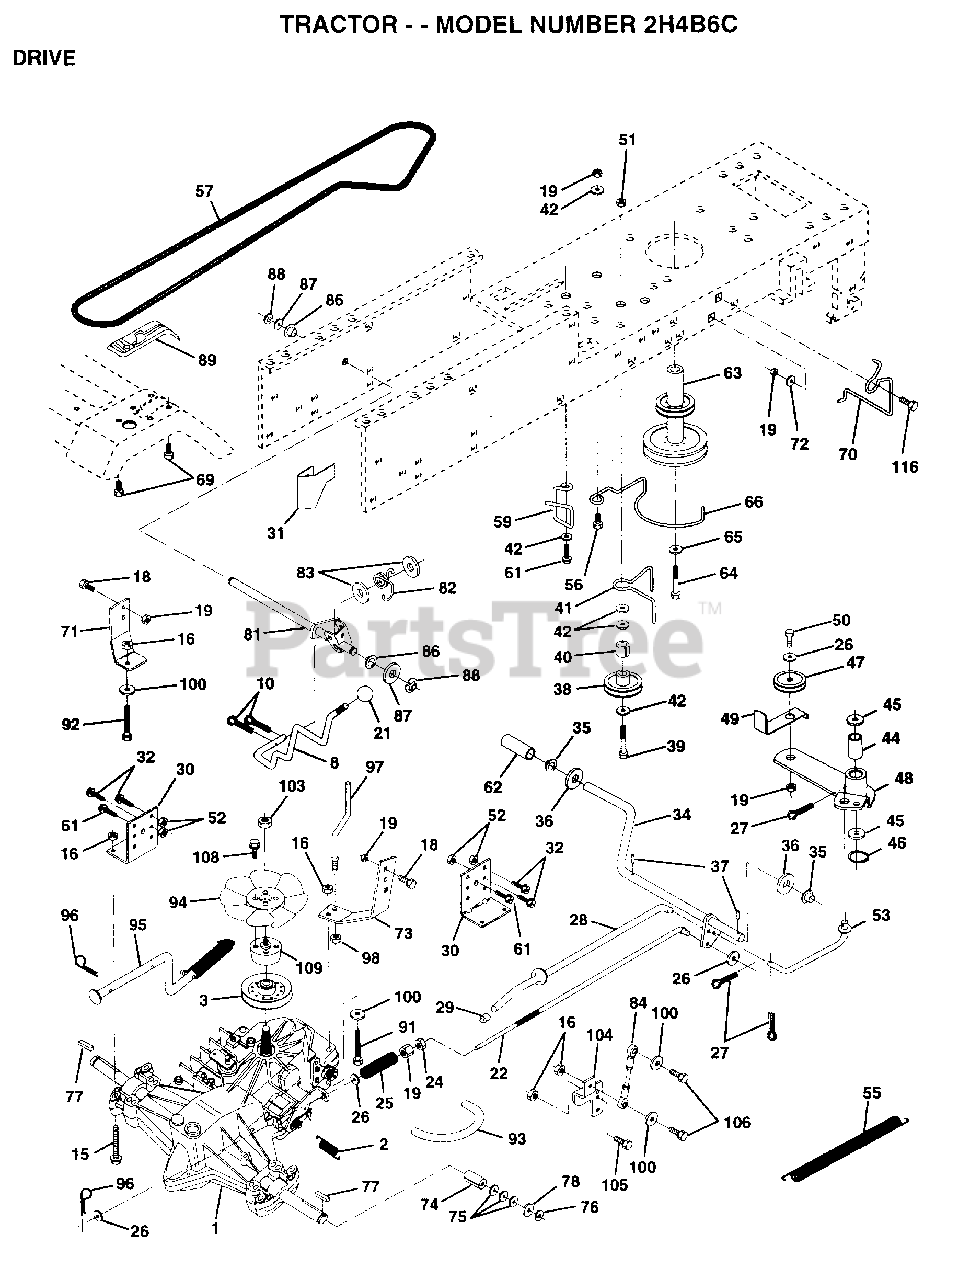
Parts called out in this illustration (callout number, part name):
1	TRANSAXLE HYD 0319-0500
2	SPRING RET BRAKE
3	PULLEY.4.20.HYDRO
8	ROD SHIFT FEND LT
10	PIN COTTER 1/8
15	BOLT.HX.FLG.5/16
16	NUT
18	BOLT
19	NUT
21	KNOB T (1/2-HOLE)
22	ROD.BRAKE.HYDRO.
24	NUT
25	SPRING ROD LT
26	WASHER
27	COTTER PIN
28	ROD.BRAKE.PARK.LT
29	PLUNGER CAP T
30	TRANSAXLE MTG BKT
31	"KEEPER,BELT LH T"
32	BOLT
34	SHAFT.PEDAL.FOOT
35	NYLON BEARING
36	WASHER LT
38	PULLEY.IDLER.FLAT
39	BOLT
40	SPACER T
41	BELT KEEPER LT
42	WASHER
44	"LY, BEARING"
45	WASHER LT
46	KLIP RING
48	ARM IDLER
49	RETAIN BELT
53	"LINK, CLUTCH T"
55	"SPRING, RETURN LT"
57	BELT-V.HYDR.84.61
59	KEEPER BELT CNTSP
61	SCREW
62	PEDAL COVER T
63	PULLEY.ENGINE
64	BOLT
65	LOCKWASHER
66	KEEPER.BELT.ENG.L
69	SCREW HEXWSH H-L
70	KEEPER BELT ENG
71	STRAP.TORQ.LH.HYD
72	WASHER
73	STRAP.TORQ.RH.HYD
74	SPACER SPLIT
75	WASHER
76	E-RING LT
77	SQUARE KEY
78	WASHER
81	SHAFT.CROSS.HYD
82	"SPRING,TORSION"
83	WASHER
84	ROD.TIE.BALL.HYD.
86	BUSHING
87	WASHER D
88	KLIP RING
92	HEX BOLT
93	"LINE FUEL HYD 4"""
94	"FAN 7"" HYDRO"
95	RETAINER M
97	KEEPER.BELT.RH.HY
98	NUT
100	WASHER M
104	ARM.CONTROL.PUMP
105	SCREW CAP 5/16-18
106	BOLT
108	SCREW.HXHD.10-20
109	ADAPTOR.FAN.HYDRO
116	BOLT RDHD 3/8-16
